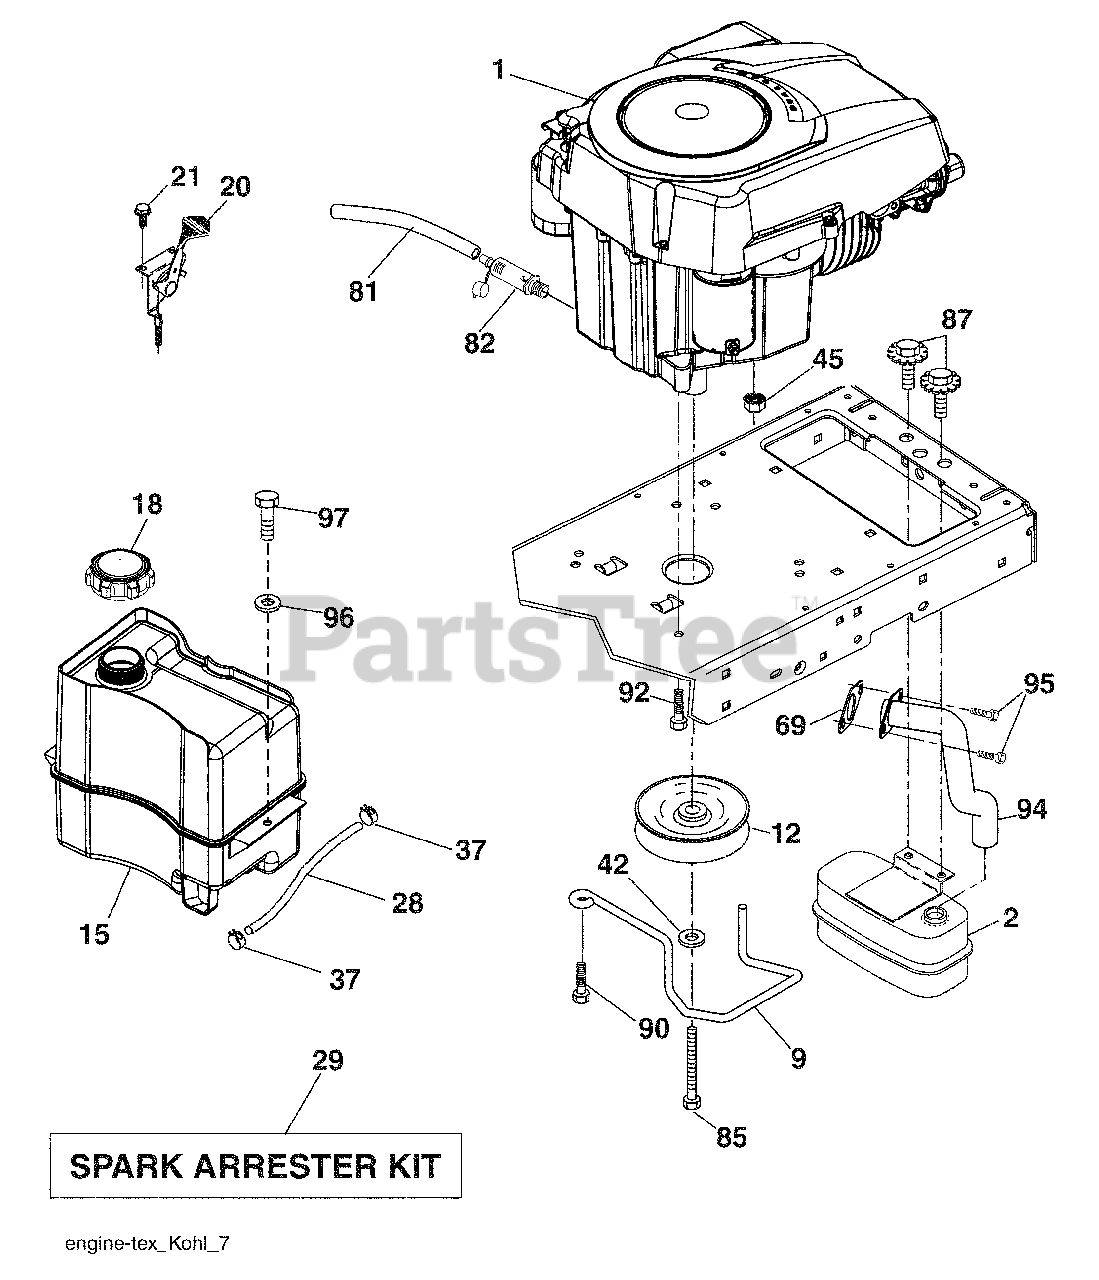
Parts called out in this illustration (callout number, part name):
9	Keeper Belt Engine
12	Pulley Engine
15	Tank Fuel
18	Cap Asm
20	Control Throttle
21	Screw # 10 x 0.750
28	Fuel Line
29	Spark Arrester Kit
37	Clamp Hose
42	Washer Lock 7/16
45	Nut Keps Hex 1/4-20 unc
81	Tube Drain Oil Easy
82	Plug Drain Oil
85	Bolt Hex 7/16-20 x 4 x Gr. 5-1.5 Thr
87	Bolt 5/16-18 unc x 3/4 w/Sems
90	Screw 3/8-16 x 1
92	Screw 3/8-16 x 1
94	Tube Exhaust
95	Screw Socket Hd. 5/16-18 x .75
96	Washer 9/32 x 7/8 x 16 Ga.
97	Screw 1/4-20 x 3/4
